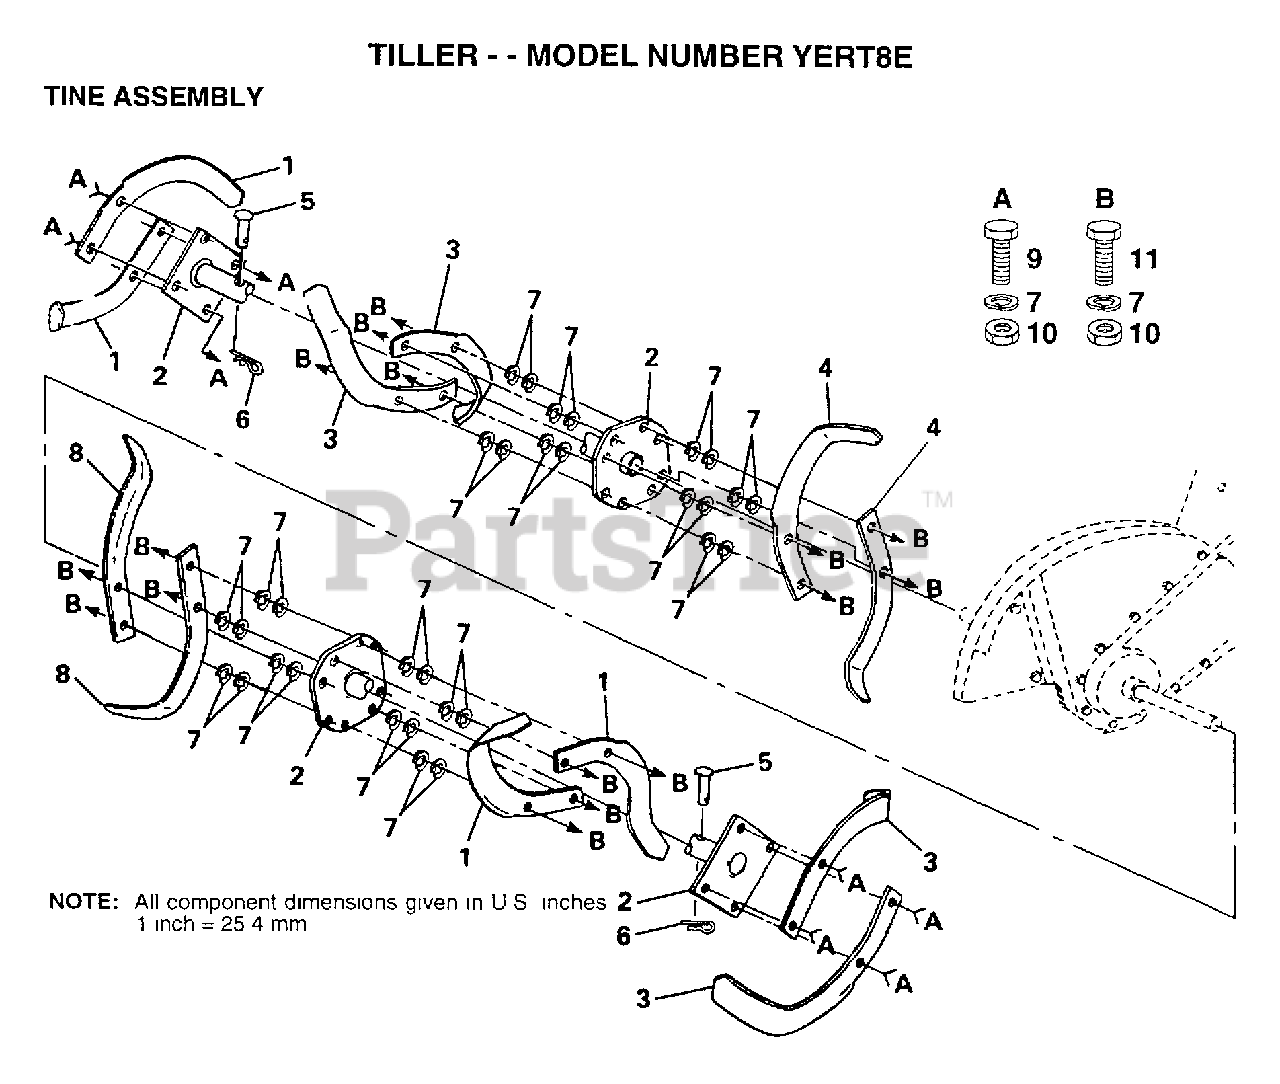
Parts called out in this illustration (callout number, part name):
1	DECAL.PNL.CTRL.
2	NAMEPLATE.HUSKEE
3	DECAL.GUARD.BELT
5	DECAL.INST.PNL.CT
6	DECAL TI
7	DECAL.SHIFT.IND.
9	DECAL TI
10	DECAL.ENG.B&S.8HP
11	DECAL.ENG.B&S.8HP
